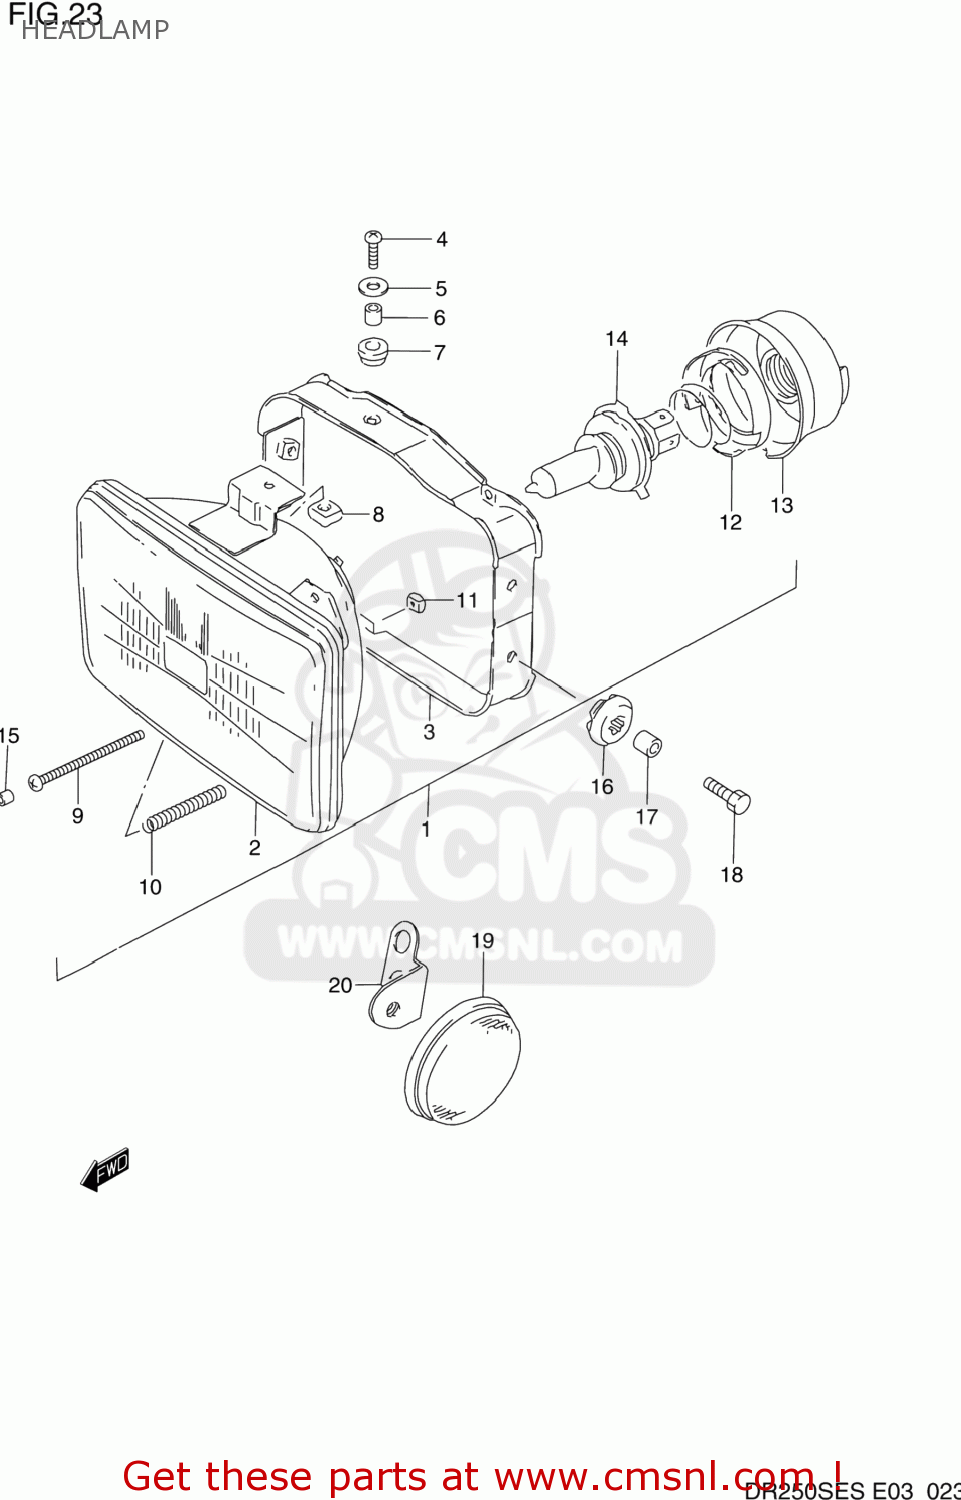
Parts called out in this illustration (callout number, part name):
1	HEADLAMP ASSEMBLY
2	LAMP UNIT
3	HOUSING
4	SCREW
5	WASHER
6	SPACER
7	CUSHION
8	NUT
9	SCREW
10	SPRING
11	NUT
12	HOLDER,BULB
13	COVER,SOCKET
14	BULB(12V60/55W,H4)
15	CAP,SCREW
16	CUSHION
17	SPACER(6.3X9.1X11.5)
18	BOLT 6X20
19	REFLECTOR,REFLEX FR
20	BRACKET
